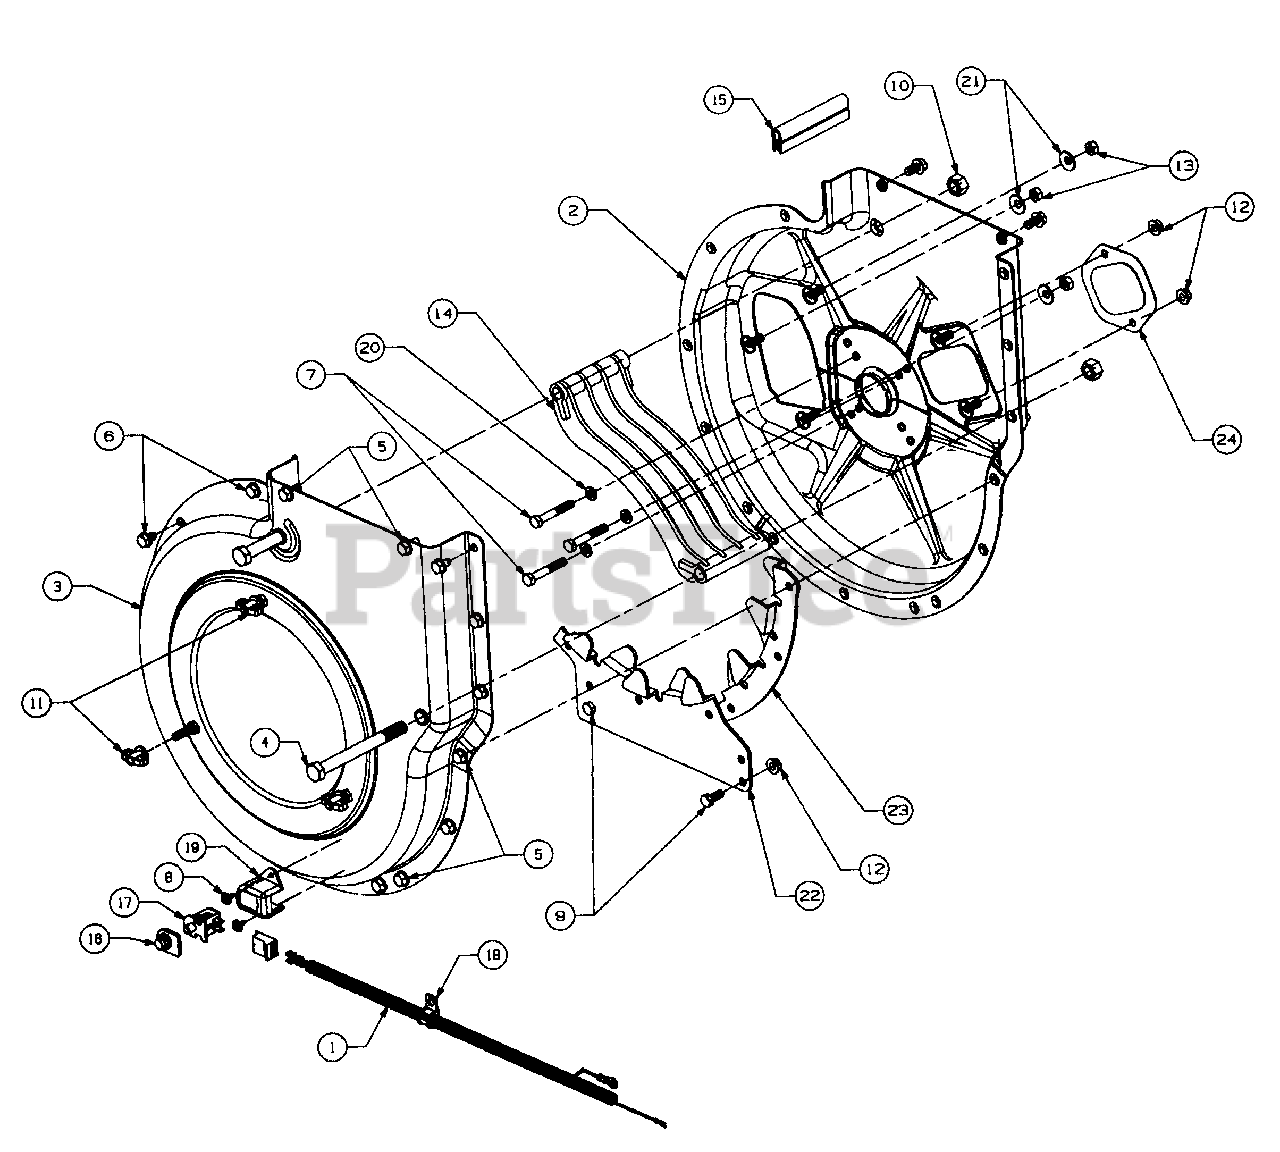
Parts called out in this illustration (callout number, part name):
1	HARNESS-CHIPPER VAC
4	SCREW-HEX
5	SCREW-HEX SELF TAP
6	SCREW-HEX SELF TAP
7	SCREW-HEX
8	SCREW- HEX SELF TAP
9	SCREW-HEX
10	NUT-HEX LOCK
12	NUT-HEX LOCK
13	NUT-HEX (GR 5)
14	SCREEN
15	SEAL-RUBBER
16	COVER-SWITCH
17	SWITCH
18	CLAMP
19	COVER SWITCH
20	WASHER-LOCK
21	WASHER-BELL
